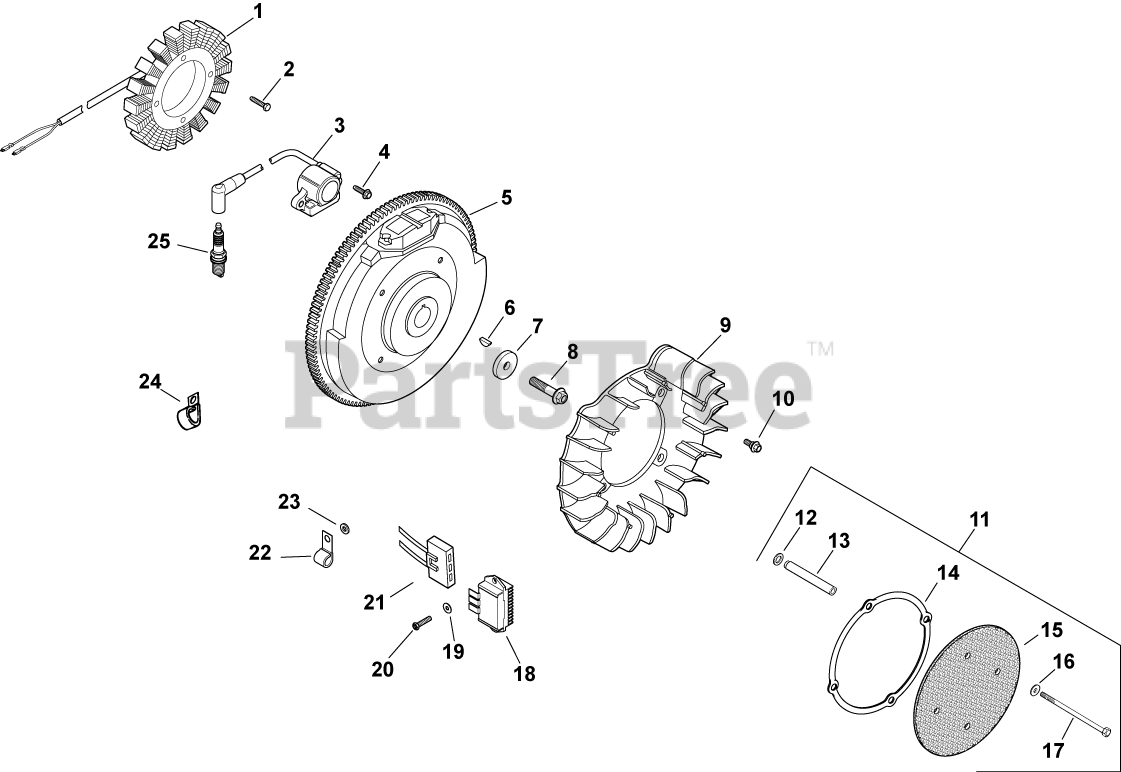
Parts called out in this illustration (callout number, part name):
1	KIT, 15 / 20 AMP STATOR
2	SCREW, M5X0.8X25 - (#25086402S)
3	MODULE, IGNITION
4	SCREW, FLG THD FRM M5X.8X20-(#25086399S)
5	FLYWHEEL ASSEMBLY (LW)-USE 24 025 58-S
6	KEY, 3/16" X 5/8"
7	WASHER, FLAT 13/32"
8	SCREW, FLG M10X1.5X45 - (#25086361S)
10	SCREW, SKT SET #10-24X1/4"
11	KIT, CHOPPER SCREEN
12	WASHER, SPRING 10 MM
14	RING, SUPPORT USE 25 141 08-S
15	SCREEN, GRASS
16	WASHER, FLAT 1/4" (O.D. 5/8")
17	SCREW, CAP M6X1.0X99.5
18	REG/RECT-15 AMP (KM)-USE 41 403 10-S
19	WASHER, FLAT 7/32"
20	SCREW, PHL HD #11-16X7/8"
21	CONNECTOR, BODY (KM)-USE 25 155 41-S
22	CLIP, CABLE
23	WASHER, FLAT 1/4" (O.D. 1/2")
24	CLIP, TUBE & WIRING (KM)
25	PLUG, SPARK (STD)
2458452-S	MODULE, SPARK ADV -USE 24 584 89-S
